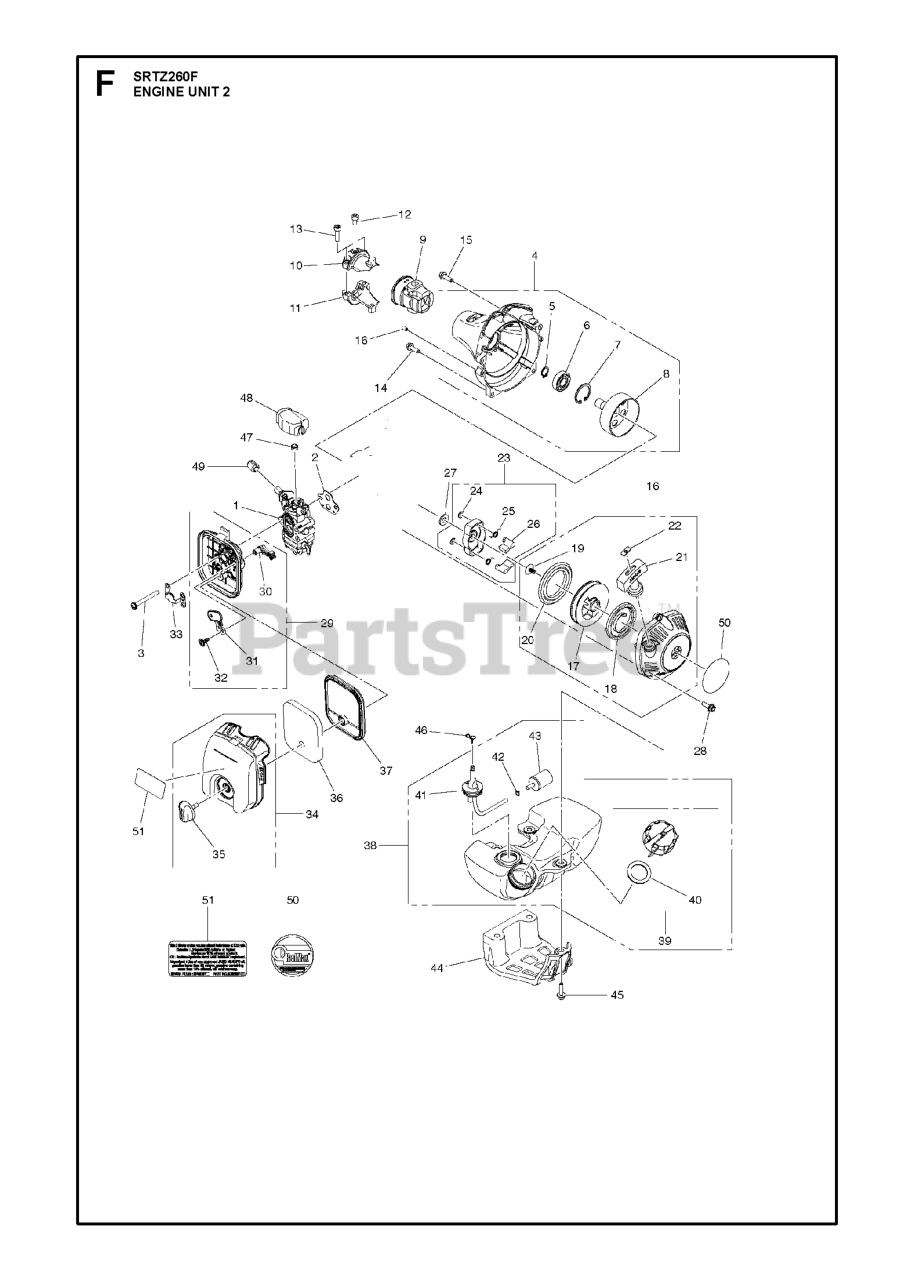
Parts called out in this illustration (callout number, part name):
1	CARBURETOR ASSY
2	GASKET CARBURETOR
4	ASSY CLUTCH COVER
8	CLUTCH DRUM ASSY
9	CUSHION UPPER
10	BRACKET UPPER M5X0.8
11	BRACKET LOWER
13	BOLT M5X20 T27
14	BOLT M5 X 16
16	STARTER ASSY
17	STARTER PULLEY
18	SPRING, SPIRAL
19	SCREW
20	ROPE
23	STARTER PULLEY ASSY
27	WASHER T2.0MM
28	BOLT M5 X 16
29	FILTER HOUSING ASSY
31	PLATE
34	COVER ASSY
35	CLEANER KNOB
36	AIR FILTER
38	ASSY TANK EVAP
39	TANK CAP
41	PIPE COMP
42	CLIP
43	FUEL FILTER
44	SKID PLATE
45	BOLT M5X25
46	CLIP
50	DECAL STARTER
51	DECAL , GASOLINE
